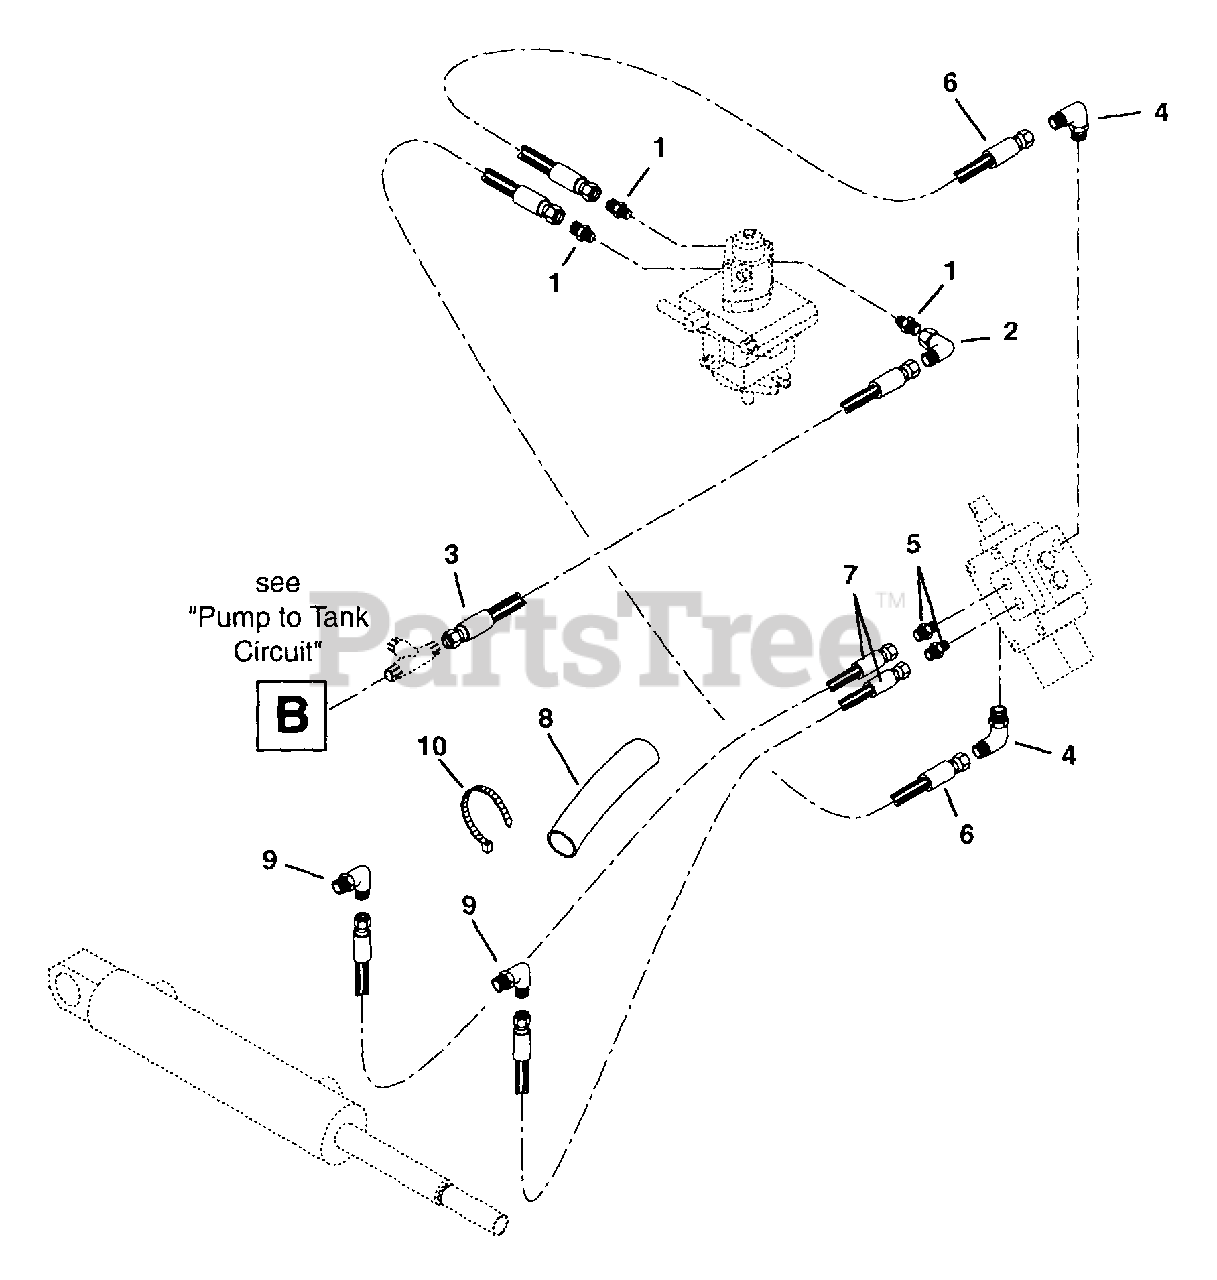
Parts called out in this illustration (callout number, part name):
2	Adapter
3	Hose-Hydraulic Valve to Tank
4	Adapter
5	Adapter
6	Hose Hydraulic .38 27.75 Long
7	Hose-Hydraulic .25 40.5" Long
8	Sleeve Protective 24"
9	Adapter
10	Cable Tie
